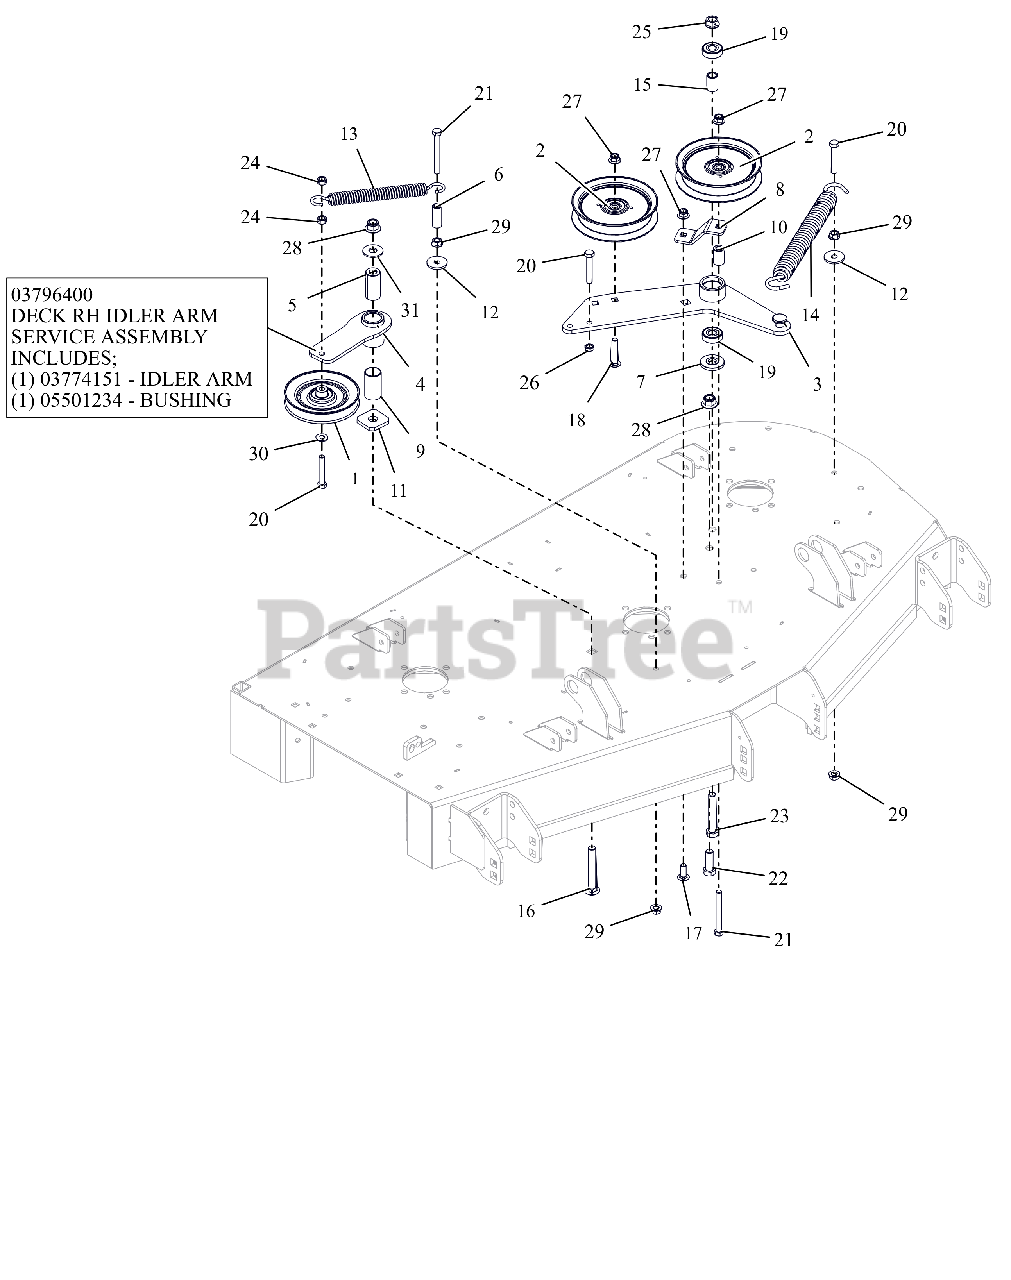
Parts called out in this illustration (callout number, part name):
1	IDLER, V-5.00"
2	IDLER, FLAT 5.00"
3	DECK PTO IDLER ARM WLDMT - BLK
4	WMT, IDLER ARM - BLACK
4	ASM, IDLER ARM (DECK)
4	BSHG, 1.00X1.125X1.937
5	BSHG, SPCR .502X.997X2.03 PM
6	SPACER, .375IDX.625ODX1.66 PM
7	SPACER, IDLER ARM
8	PTO FIXED IDLER MTG BRKT-ORG
9	BSHG, 1.00X1.125X1.937
10	BUSHING, SLV .380X.750X1.190
11	WSHR-FLT .640X1.75X.250
12	WSHR-FL-STL .406X1.375X.135 YZ
13	SPRING, EXTENSION
14	SPRING, EXTENSION
15	SPACER .510 X .75 X 1.1485
16	@BLT-RDHDSQNK .50-13X3.50 G5YZ
17	@BLT-RDHDSHSQNK.38-16X1.0 G5YZ
18	BLT-RDHDSQNK .38-16X2.00 SHTYW
19	BRG-BALL .500X1.38X.437
20	@BLT-HEX .38-16X2.25 GR5 YWZC
21	@BLT-HEX .38-16X3.25 GR5 YWZC
22	@BLT-HEX .50-13X1.50 GR5 YWZC
23	@BLT-HEX .50-13X3.00 GR5 YWZC
24	@NUT-LK-CTR .38-16 YWZC
25	NUT-LK-CTR-FLG .50-13 YWZC
26	NUT-HEX-JAM .375-16 YWZC
27	@NUT-LK-NYL-FLG .38-16 YWZC
28	@NUT-LK-NYL-FLG .50-13 YWZC
29	@NUT-SPNLK-FLG .375-16 YWZC
30	@WSHR-FL-STL.406X.812X.065 YWZ
31	@WSHR-FL-STL.563X1.38X.109YWZC
